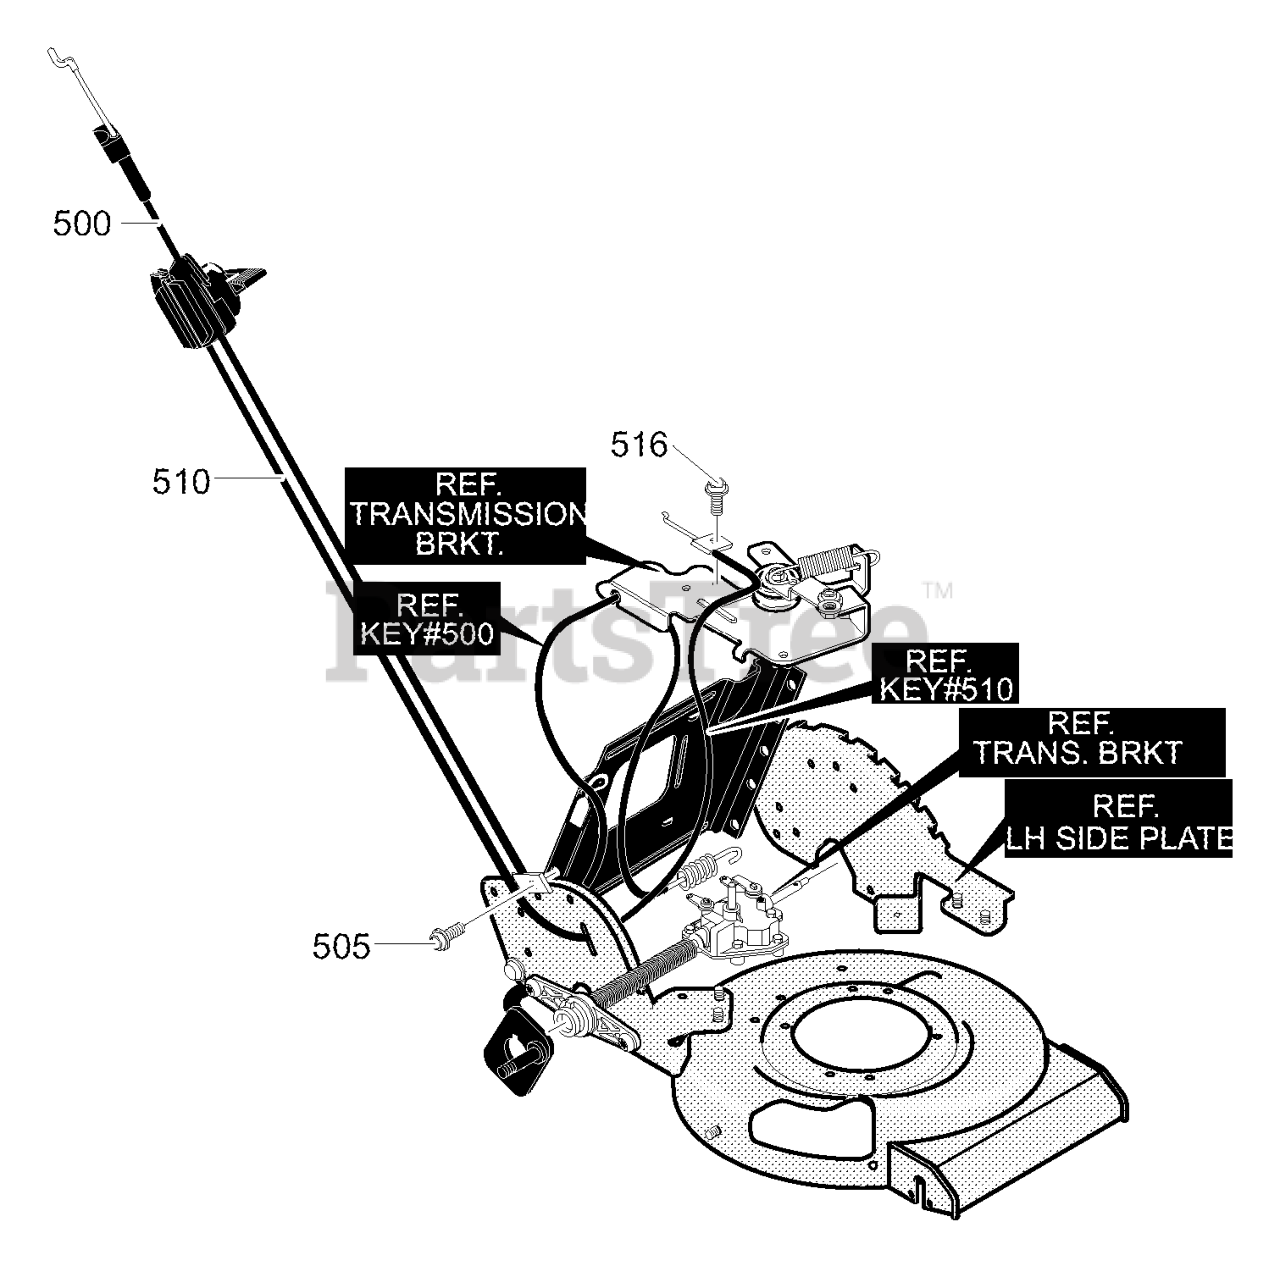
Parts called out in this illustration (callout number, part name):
500	Cable, Drive Assy.
505	Screw, 10-16x.50
510	Cable, Shifter Speed Ctl
516	Screw, 10-32x.62
